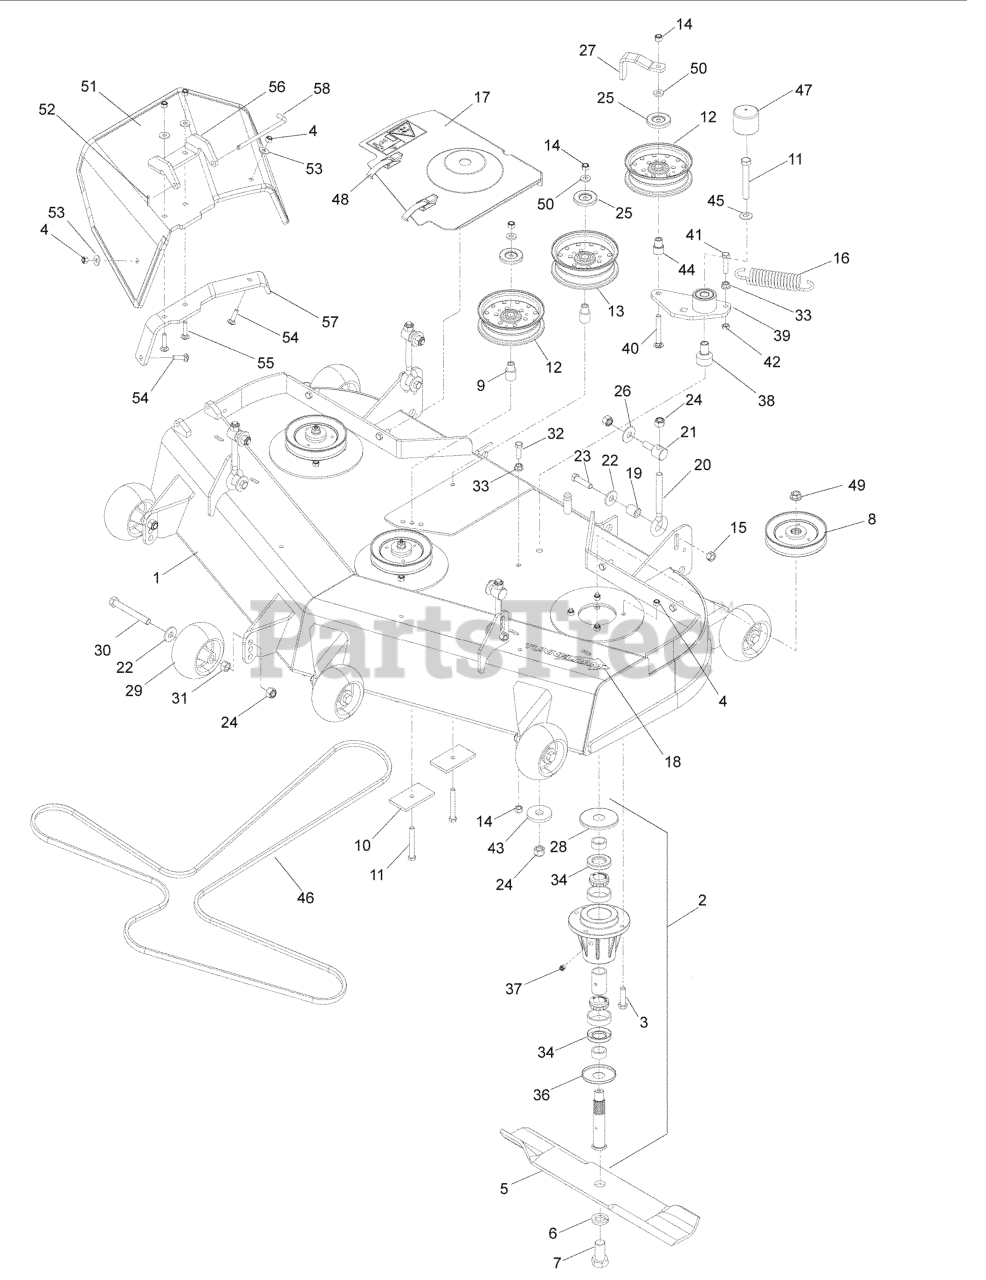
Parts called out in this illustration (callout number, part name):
1	DECK W/DECALS 52" HUS
2	HOUSING ASM, 52/61
3	HCS 5/16C X 1 1/4
4	NUT 5/16 NYLOC
5	BLADE OEM 18"
6	LOCKWASHER 5/8
7	HCS 5/8F X 1 1/4
8	PULLEY, 52
9	IDLER BUSHING
10	SUPPORT PLATE
11	HCS 1/2C X 3 1/4
12	IDLER PULLEY
13	PULLEY - IDLER, 6IN WIDE
14	NUT 3/8-16 NYLOC
15	NUT 7/16C CENTERLOCK
17	52" BELT SHIELD ASM - RH
18	DECAL, TUNNEL RAM 8"
21	SWIVEL, DECK HEIGHT ADJ
22	WASH USS FLAT 1/2
23	HCS 7/16 - 14 X 1 3/4
24	NUT 1/2-13 HEX NYLOC ZD
25	DUST SHIELD
26	WASHER-.533IDX1.37OD
28	TOP DUST CAP
29	GAUGE WHEEL
30	HCS 1/2-13 X 4 GR 5 ZD
31	NUT HEX 1/2
32	HCS 3/8C X 1 1/4 GR5
33	NUT 3/8C WHIZ
34	SHAFT SEAL
35	BOTTOM DUST CAP
36	PLUG-VENTED
37	ZERK
38	PIVOT, BEARING
39	ARM-IDLER W/BRG
40	RHSNB 3/8-16 X 2.75
41	HCS 3/8-16 X 1-1/2
42	NUT 3/8-16 HEX JAM
43	WASHER, SUPPORT
44	BUSHING, IDLER
45	CONTACT BELLSPR 1/2
46	BELT, DECK IZ/MIDMAX ONLY
47	CAP, VINYL
48	DRAW LATCH
49	NUT FLANGE 3/4-16
50	WASHER, 3/8 THICK
51	CHUTE, RUBBER DISCHARGE 52/61"
52	RP_COTTER PIN 1/8 X 3/4
53	WASHER 5/16 FLAT
54	BOLT, CARRIAGE 5/16X1-1/4
55	RHSNB 5/16-18 X 1-1/2 GR 5 ZD
56	PIVOT BRACKET - RUBBER CHUTE
57	BRACKET, REINF-CHUTE
58	PIN, CHUTE PIVOT
